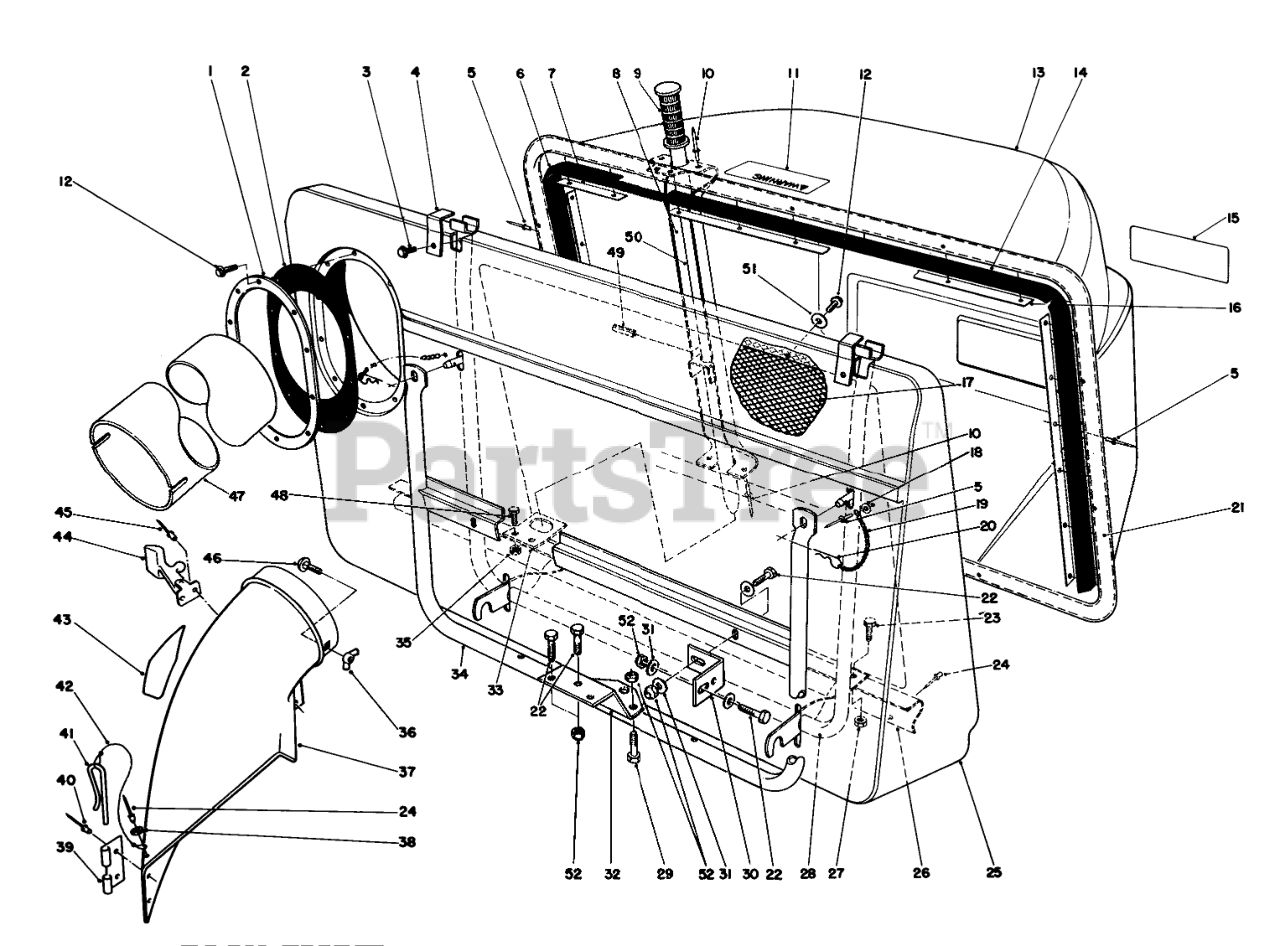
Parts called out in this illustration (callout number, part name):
1	RING-RETAINING
2	RING-RETAINER, RUBBER
3	SCREW-HWH
4	RETNR PIVOT BRKT
6	RH BAG SEAL
7	RETNR TOP EXT.
8	DUMP HDLE CHANL WA
11	Decal Warning
12	SCREW-HWHTF
13	REAR GRASS BASKET
14	Seal-Bag LH.
15	EASY EMPTY BAG DECAL
16	BAG RETNR EXT.
17	Screen Bag
18	WASHER
19	10 LINK CHAIN W/O HOOK
20	PIN-HAIR
21	BAG SUPT ASM FRM
22	SCREW-HH
23	SCREW-HH
24	RIVET-BLIND
25	Bag Front
26	FRAME SUPT BRKT B
27	NUT-LOCK, CONE
28	Bag Frame
29	SCREW-HH
30	MTG BRACKET
31	WASHER-PLAIN
32	MTG PLATE B
33	Hanger-Frame Lower
34	BAG SUPPORT WA
35	NUT-LOCK, CONE
36	NUT-WING SPECL
37	Chute Assy. (Incl. Ref. #24, 38-45)
38	WASHER-PLAIN
39	BRACKET-MOUNTING, CHUTE
40	RIVET-BLIND
41	PIN-LOCKING, CHUTE
42	LANYARD
43	DECAL-DANGER
44	Latch-38"
45	RIVET-POP
46	BOLT-CARR
47	TUBE(ROUND&LONG)
48	SCREW-HH
49	PIN-ROLL
50	DUMP HANDLE ASM
51	WASHER-FLAT
52	NUT-LOCK, NI
